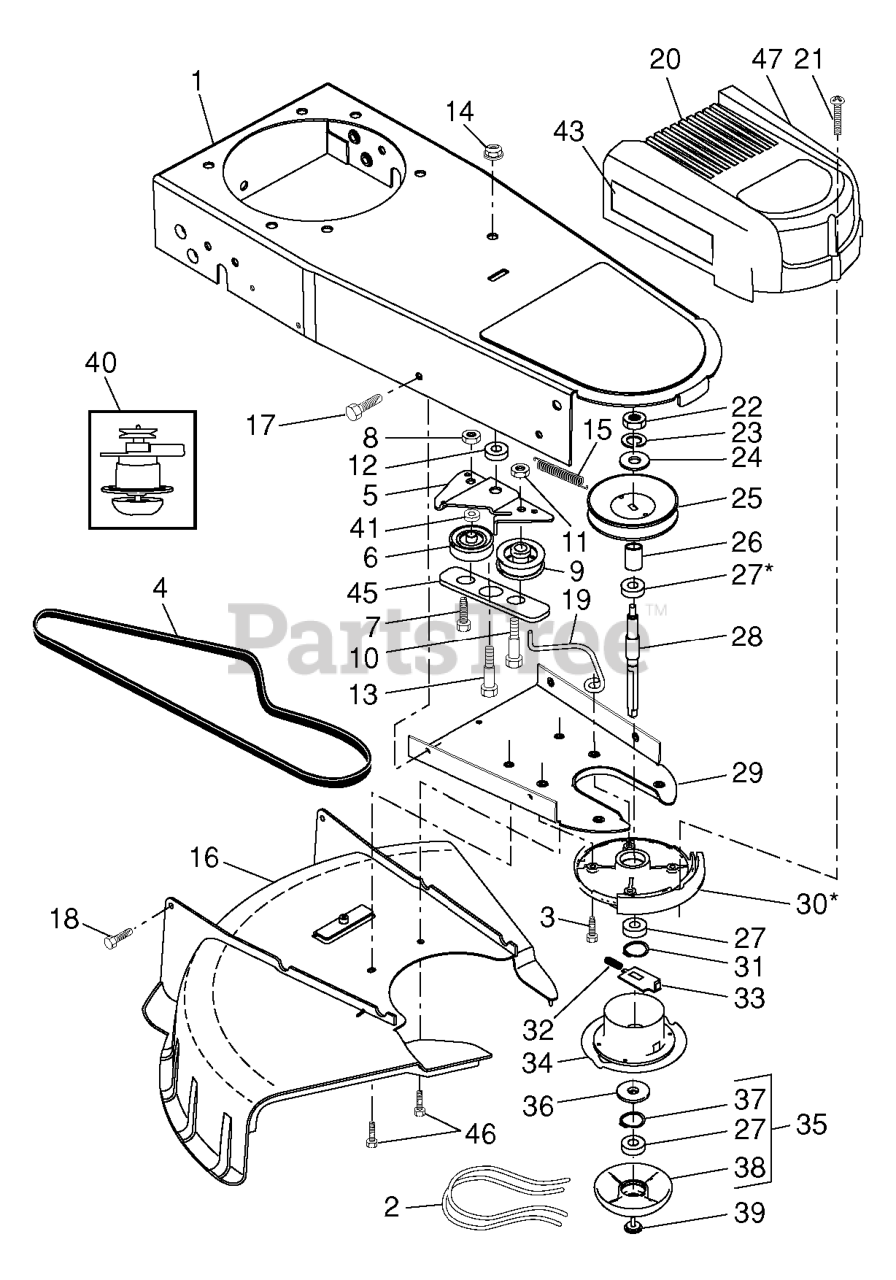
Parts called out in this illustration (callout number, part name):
1	SHIELD, LOWER, 54"
2	SHIELD, LOWER, 60"
3	PULLEY, DRIVE, 54"
4	BELT, DRIVE RAKE/SLICER DFS
5	FRONT WEIGHT CAST PZ DFS
6	BRACKET.MTG.CNTRWT.SIX.BLK
7	SPACER, PULLEY
8	KNOB W/STUD
9	DECAL, NO STEP
10	BAFFLE, RH, BLACK
11	BAFFLE, LH, BLACK
12	ROD.LATCH.BLK
13	HAIRPIN #4
14	U-BOLT.SQUARE.1/2-13.GR5
15	BOLT 5/16C X 2 1/2
16	BOLT 5/16C X 3/4" CARRIAGE
17	RHSNB, 1/4-20 X 1, GR5
18	5/16-18 NYLOC FLANGE NUT
19	NUT.1/4-20.HEX.NYLOC.ZD
20	NUT, 1/2-13 HEX FLG NYLOC ZD
21	WASH 5/16 DISC SPRING ZD
22	WASHER 3/8 SAE FLAT
